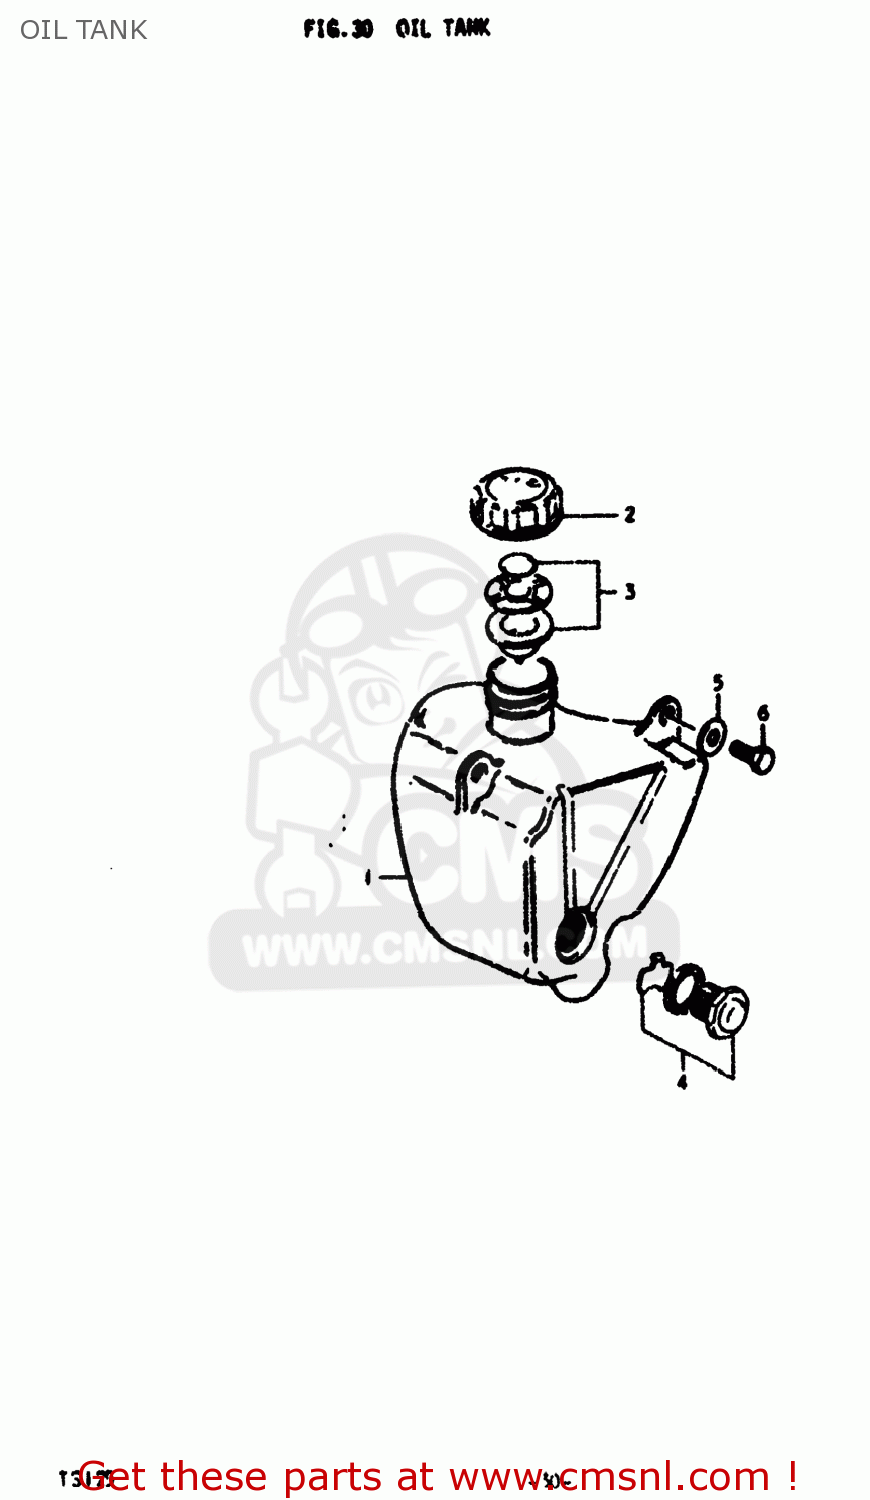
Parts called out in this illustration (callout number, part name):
1	TANK,OIL
2	CAP,OIL TANK
3	GASKET SET (NAS)
4	LENS SET,OIL LEVEL
5	WASHER
6	BOLT, UPPER
